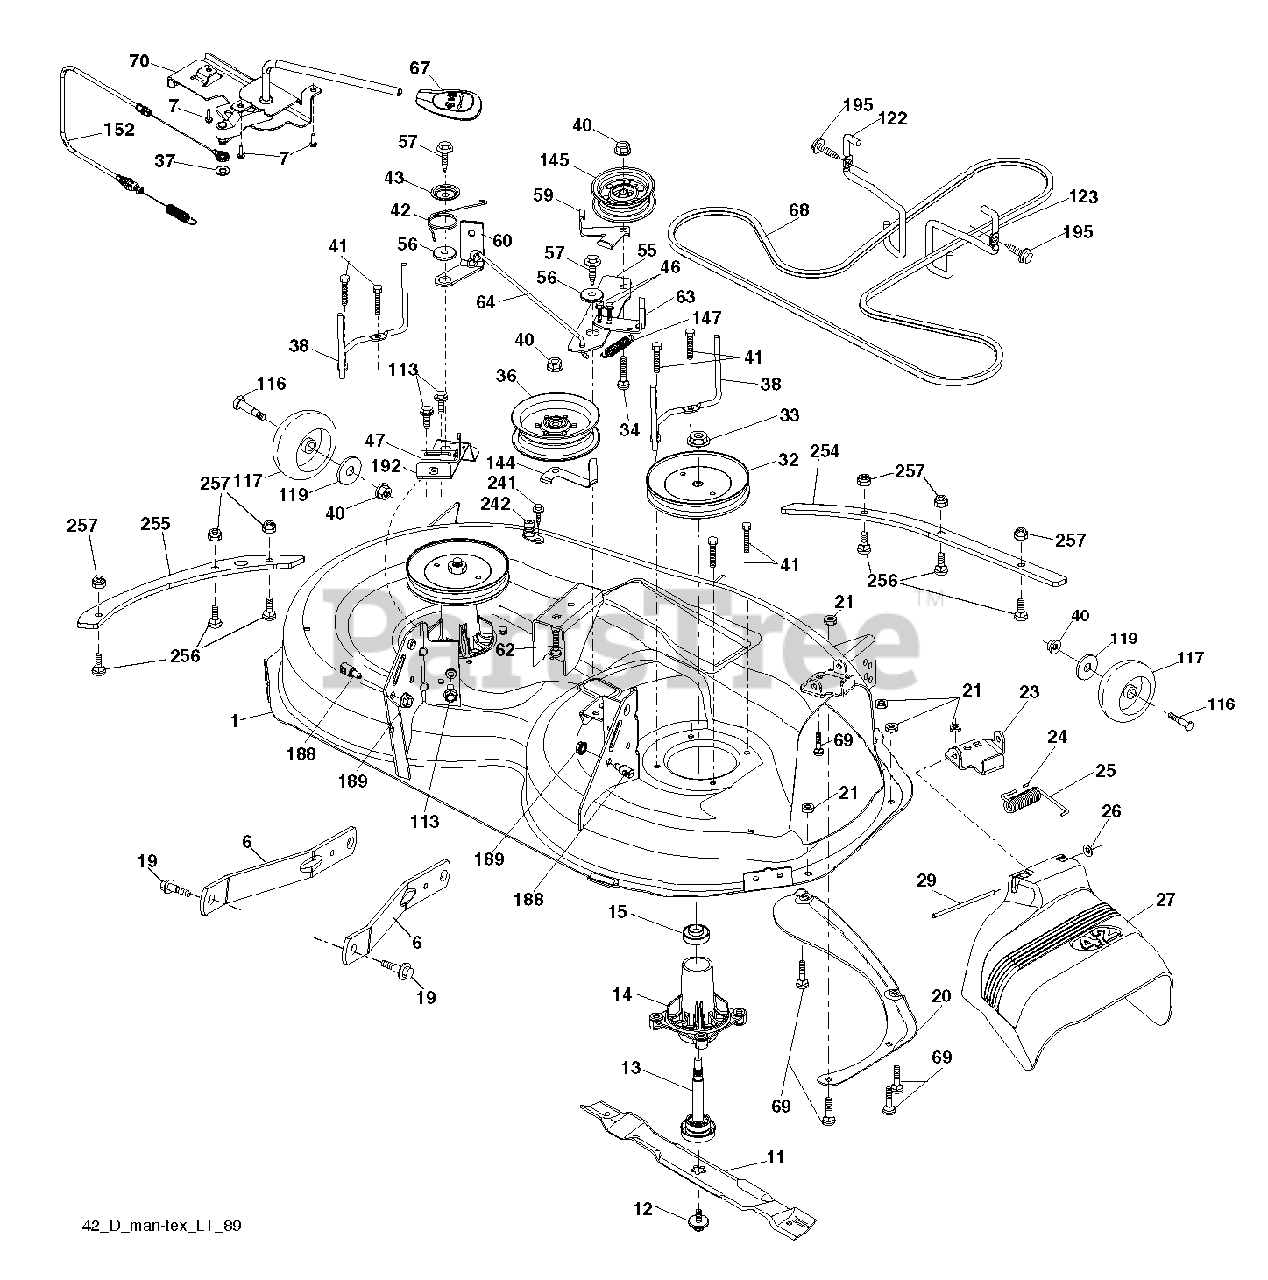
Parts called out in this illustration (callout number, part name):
1	Mower Deck Assembly, 42"
6	ARM.SUSPENSION.MOWER.R
7	SCREW.#10 X 0.750.BOS (2 2)
11	42" HI-LIFT BLADE
12	Screw, 7/16 X 20 X 1"
13	Mandrel Assembly, Non-Greaseable
14	HOUSING.MANDREL.4PT.
15	Extended Mandrel Bearing, Top
19	BOLT.SHOULDER
20	BAFFLE.VORTEX
21	LOCKNUT
23	BRKT.DEFLECTOR.38"2005+
24	CAP-SLEEVE LT
25	SPRING.TORSION.DEFLECT
26	NUT PUSH M
27	SHIELD.DEFLECTOR.MOWER.42"BLAC
29	ROD.HINGE
32	PULLEY.MANDREL.5.438.PD
33	NUT.FLANGE.LOCK.TOP
34	BOLT.3/8-16X1.50
36	PULLEY.IDLER.2006
38	KEEPER.BELT.MANDREL.PULLEY
40	NUT LOCK FLG 3/8-16 UNC
41	Hex Washer Head Bolt, .313-18 X 1.19
42	SPRING.TORSION.BRAKE
43	SRPING.TORSION.RETAINE
46	SCREW.1/4-20X5/8
47	BRKT.CLUTCH.CABLE
55	IDLER.ARM.42"
56	SPACER.RETAINER
57	SCREW 3/8-16X1
59	GUARD, BELT
60	ARM BRAKE MOWER
62	BOLT
64	LINKAGE.BRAKE.ASM.ZINC
67	HANDLE.CLUTCH.CABLE.LT
68	BELT.DECK.DRIVE.42"
69	BOLT
70	CLUTCH.ASM.MANUAL.LT.PRED
113	BOLT.5/16HEX.WHS.HD
116	BOLT M
117	WHEEL.GAGE.HALF.SPOKED
119	WASHER
122	KEEPER BELT ENGINE LH
123	KEEPER BELT RH
144	KEEPER.BELT.MOWER
145	PULLEY.IDLER.48"PRIMARY
147	RETURN SPRING
152	CABLE.MECHANICAL.CLUTCH
188	STUD.FASTNER.W/ANTI-ROTATE
189	NUT LOCK HEX FLANGE 5/16-18
192	BRKT.BRAKE.STAND.LH.
195	SCREW, 3/8-16X3/4
241	SCREW.TT.#10-32X.5.3/8.FLANGE
242	PORT.WASHOUT
254	Front Reinforcement Plate, 42" Deck.Ftx498
255	Side Reinforcement Plate, 42"
256	RHSNB, 1/4-20 X 1, GR5
257	NUT T
